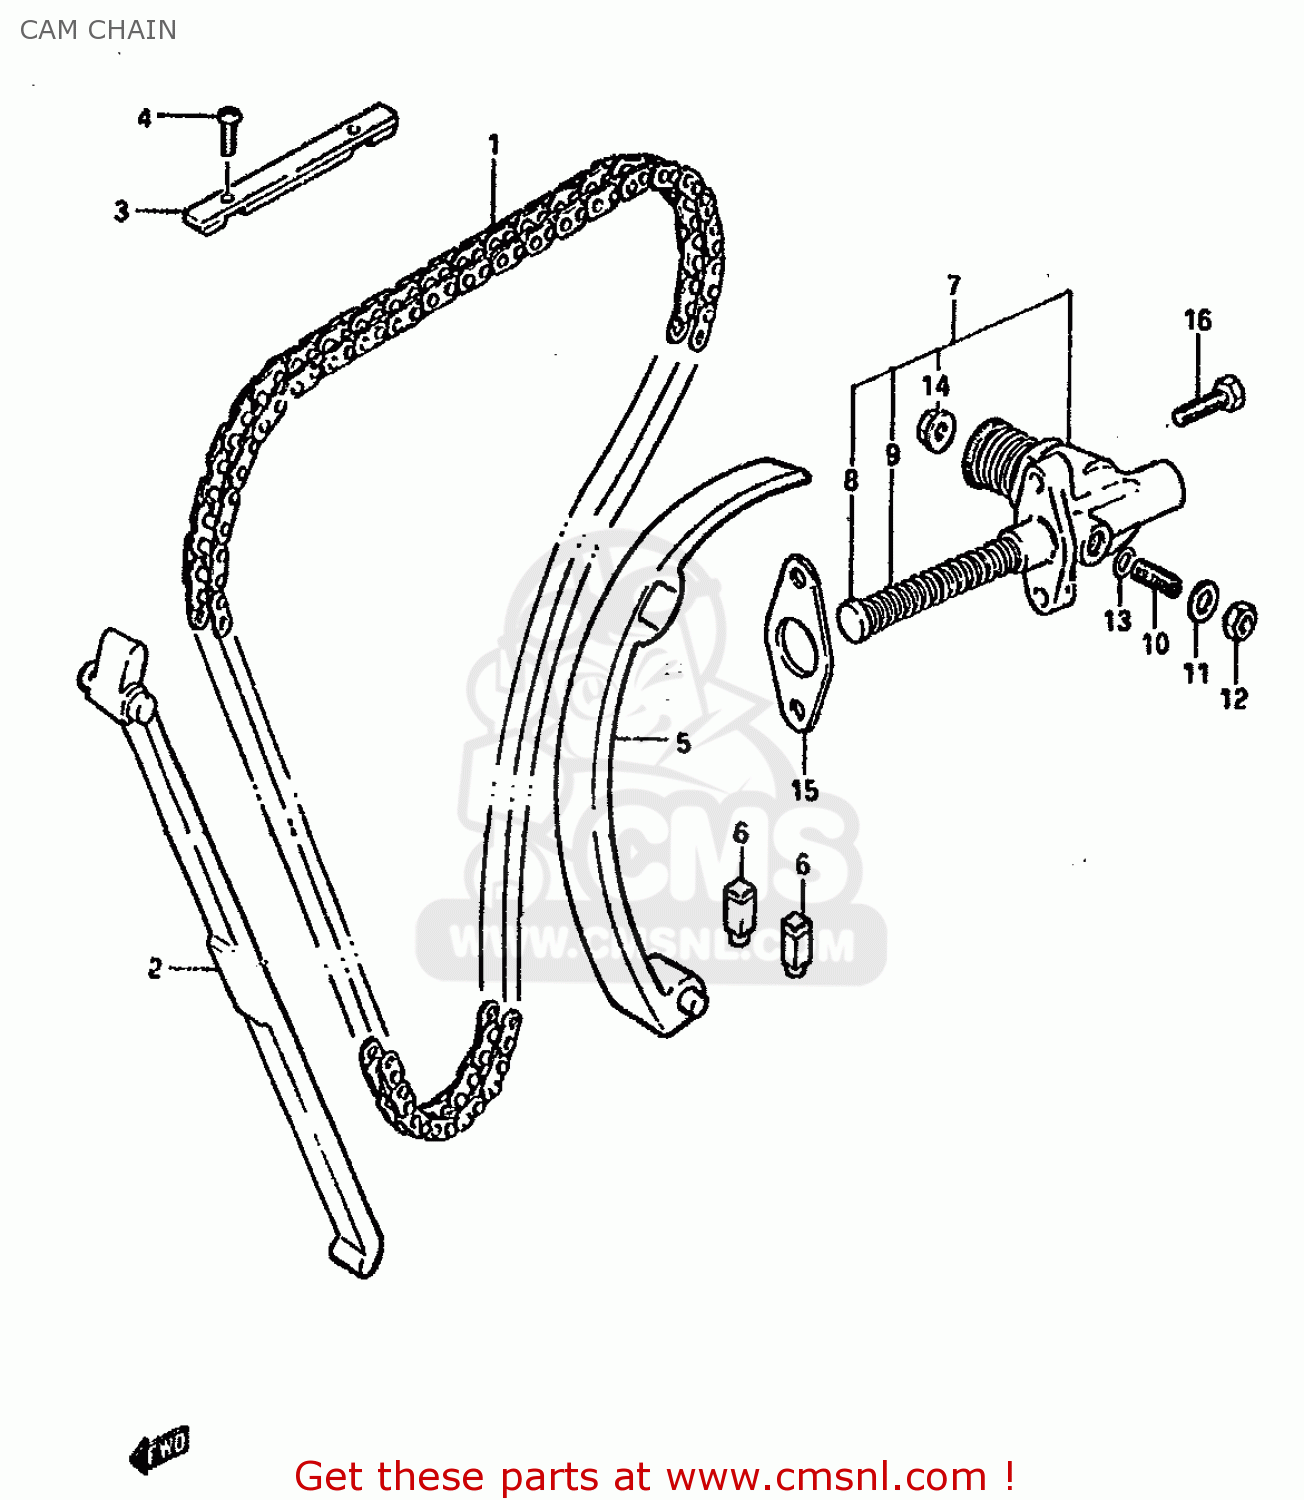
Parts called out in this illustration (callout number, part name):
1	CHAIN,CAMSHAFT DRIVE
2	GUIDE,CAM CHAIN NO.1
3	GUIDE,CAM CHAIN NO.3
4	SCREW
5	TENSIONER,CAM CHAIN
6	CUSHION,CAM CHAIN TENSIONER
7	ADJUSTER ASSEMBLY,TENSIONER
8	ROD,PUSH
9	SPRING
10	SCREW
11	WASHER
12	NUT
13	O-RING
14	NUT
15	GASKET,TENSIONER ADJUSTER (MCA)
16	SCREW (6X25)
